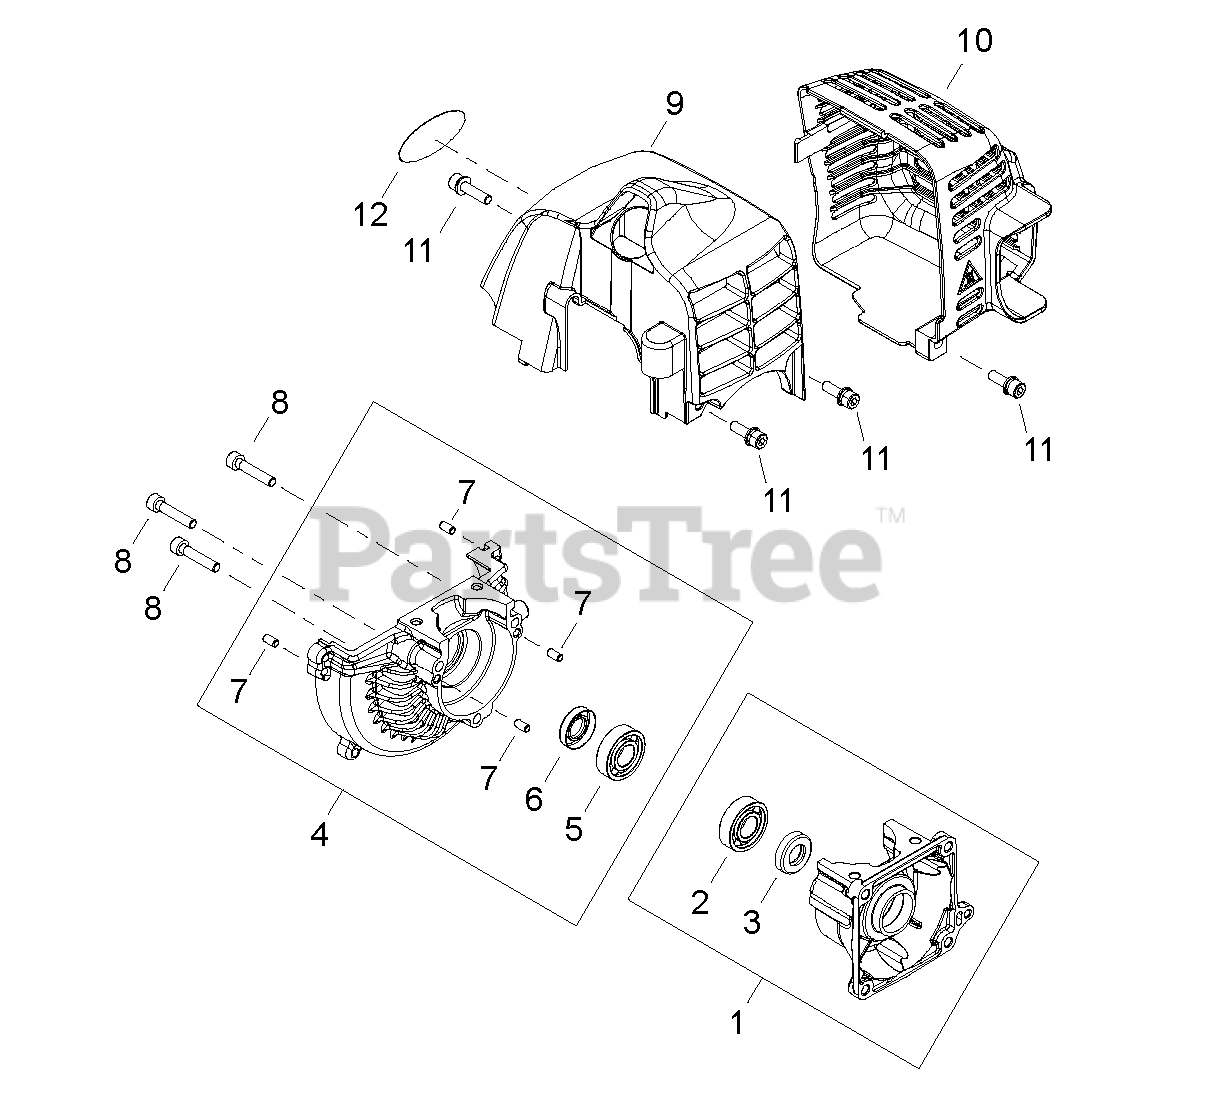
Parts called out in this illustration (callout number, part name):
1	CRANKCASE ASSY - REAR
2	BEARING, BALL - 6201C3
3	SEAL, OIL
4	CRANKCASE ASSY - FRONT
5	BEARING, BALL - 6201C3
6	SEAL, OIL
7	PIN - LOCATING
8	SCREW - 5X25
9	COVER, ENGINE
10	COVER, MUFFLER
11	SCREW - 5X20
12	LABEL - MODEL 282
